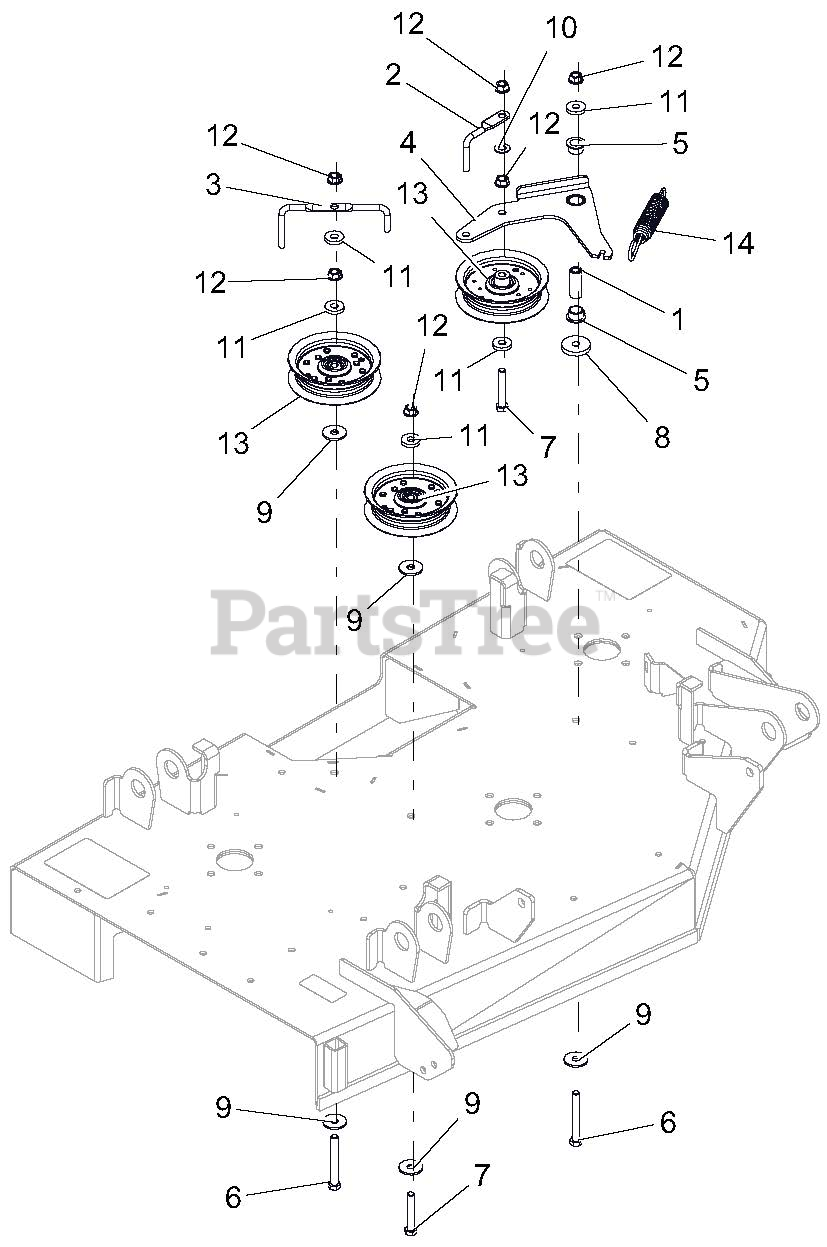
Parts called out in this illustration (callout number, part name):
1	SPCR, .375IDX.625ODX1.66 PM
2	WIREFORM, BELT FINGER
3	FINGER, BELT
4	WLDMT, IDLER ARM
5	BSHG, FLANGE .625 x .75 x .50 x 1.00
6	BLT-HEX .38-16X3.00 GR5 FTH YWZC
7	BLT-HEX .38-16X2.25 GR5 YWZC
8	WSHR-FL-STL .406X1.50X.245 YWZC
9	WSHR-FL-STL .406X1.25X.10 YWZC
10	WSHR-FL-STL.406X.812X.065 YWZ
11	WSHR-FL-STL .406X1.00X.188 YWZC
12	NUT, LK-TOP-FLG .38-16 YWZC
13	ASM, IDLER 4"
14	SPRG, EXTENSION
